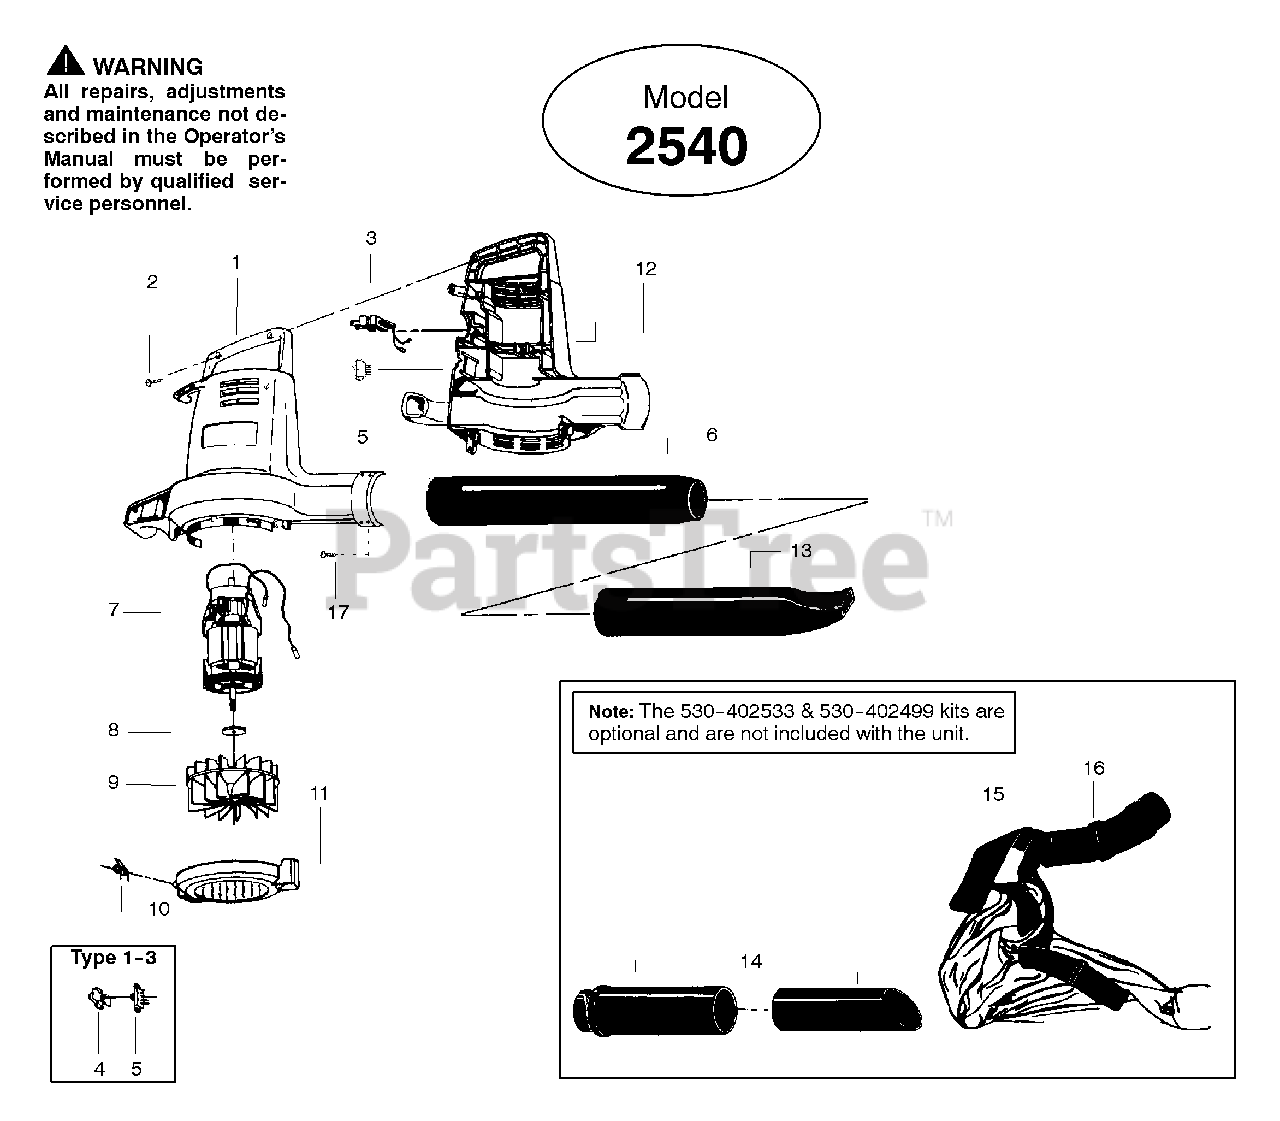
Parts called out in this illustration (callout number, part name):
1	Housing Set Type 1
1	Housing Set Type 2
1	Housing Set Type 3
1	Housing Set Type 4
3	Wire Harness Type 1 & 2
3	Wire Harness Type 3
3	Wire Harness Type 4
4	Switch Cover (Type 1-3)
5	Switch Type 1 & 2
5	Switch Type 3
5	Switch Type 4
6	Blower Tube Type 1
6	Blower Tube Type 2,3,4
7	Motor Ass'y. Type 1 & 2
7	Motor Ass'y. Type 3,4
9	Impeller Type 1 & 2
9	Impeller Type 3,4
11	Assy-Cover Spring
12	Pad (Type 1,2)
13	Nozzle Type 1,
13	Nozzle Type 2,3,4
14	Vacuum Tube Kit Type 1
14	Vacuum Tube Kit Type 2,3,4
15	Kit-Vac Bag Type 1
15	Kit-Vac Bag Type 2,3,4
16	Elbow (Type 1 only)
